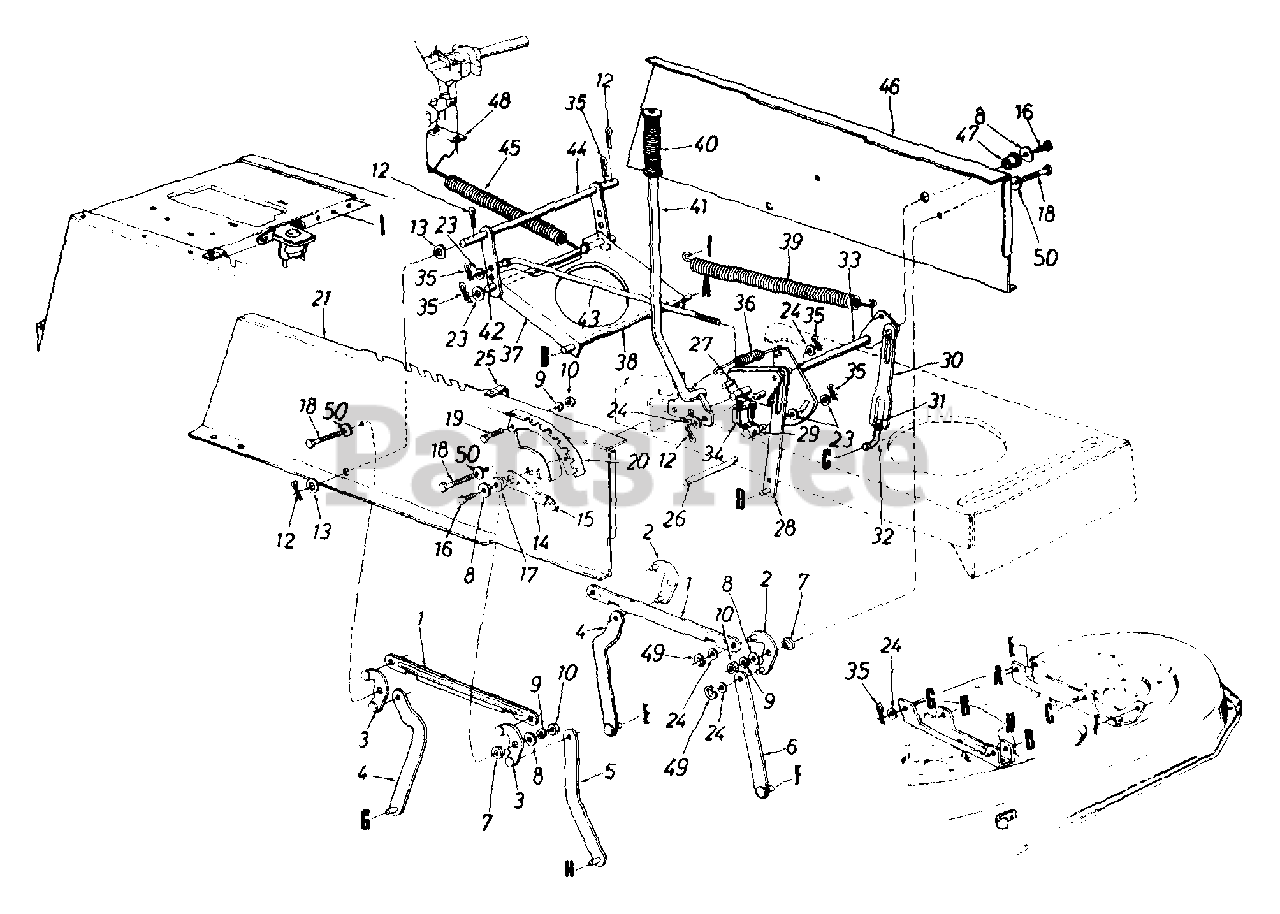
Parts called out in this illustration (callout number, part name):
3	Pivot Link Ass'y. - R.H.
7	Shld. Spacer .318" I.D.
8	Fl-Wash. .344" I.D. x .62" O.D.
9	L-Wash. 5/16" I.D.
10	Hex Nut 5/16-18 Thd.
12	Cotter Pin 1/8" Dia.
13	Fl-Wash. .635" I.D. x 1.0" O.D.
14	Height Adj. Stop Lever Ass'y.
16	Hex Wash. TT-Tap Scr. 5/16-18 x .75" Lg.
17	Flange Brg. .63" I.D.
18	Hex Wash. Hd. Scr. 5/16-18 x .875" Lg.
19	Hex Bolt 5/16-18 x .75" Lg.
20	Index Brkt.
24	Fl-Wash. .531" I.D. x .93" O.D.
26	Running Board Rod
27	Hex Wash. Hd. Tap Scr.
31	Hex Nut 1/2-20 Thd. (Gr. 5)
32	Lift Link Adjuster
35	Inter. Cotter Pin 3/8" Dia.
36	Extension Spring
39	Extension Spring
40	Grip (Lift Handle)
41	Deck Lift Handle Ass'y.
42	Shaft 3/8" Dia. x 9.34" Lg.
43	Disengagement Rod
44	Stabilizer Shaft Ass'y.
45	Extension Spring 7.58" Lg.
46	Upper Frame - L.H.
47	Flange Brg. .632" I.D.
48	Spring Retainer Brkt.
49	"E"-Ring
50	Bell-Wash. .325" I.D.
17622C-0637	FRAME-UPPER RH SID - POWDER BLACK (0637)
17622C-0638	FRAME-UPPER RH SID - MTD/TROY-BILT RED (0638)
